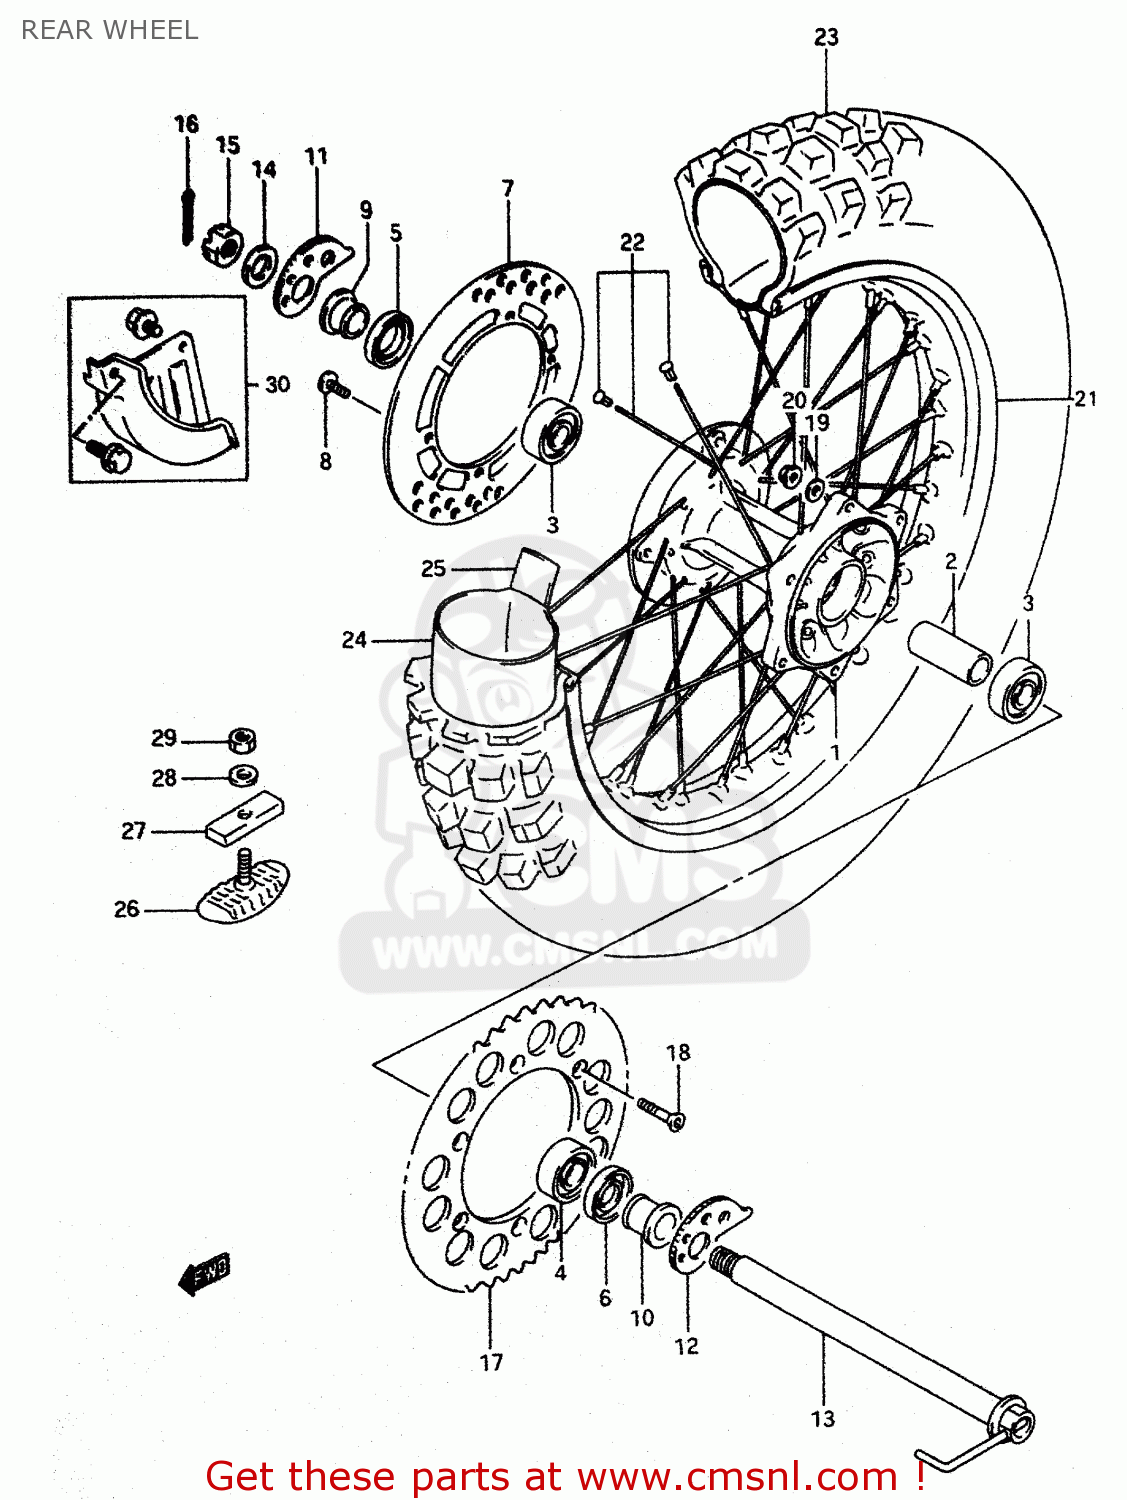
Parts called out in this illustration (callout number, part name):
1	HUB,REAR WHEEL
2	SPACER,RR HUB BEARING
3	BALL BEARING
4	BEARING
5	SEAL,OIL(26X42X8)
6	SEAL,OIL(26X47X5)
7	DISC,RR BRAKE
8	BOLT,BRAKE DISC
9	SPACER,RR AXLE,R
10	SPACER,RR AXLE,L
11	ADJUSTER,CHAIN,R
12	ADJUSTER,CHAIN,L
13	AXLE,RR
14	WASHER(19X32X3.2)
15	NUT
16	PIN,COTTER
17	SPROCKET,RR(NT:43)
18	SCREW(8X33.5)
19	WASHER
20	NUT
21	RIM,RR WHEEL(18X2.15 AL)
22	SPOKE SET,RR WHEEL
23	TIRE COMP,REAR 110/100-1
24	TUBE,INNER
25	PROTECTOR,INNER TUBE
26	STOPPER,BEAD(2.15)
27	CUSHION,BEAD STOPPER
28	WASHER
29	NUT
30	COVER SET,RR BRAKE DISC
